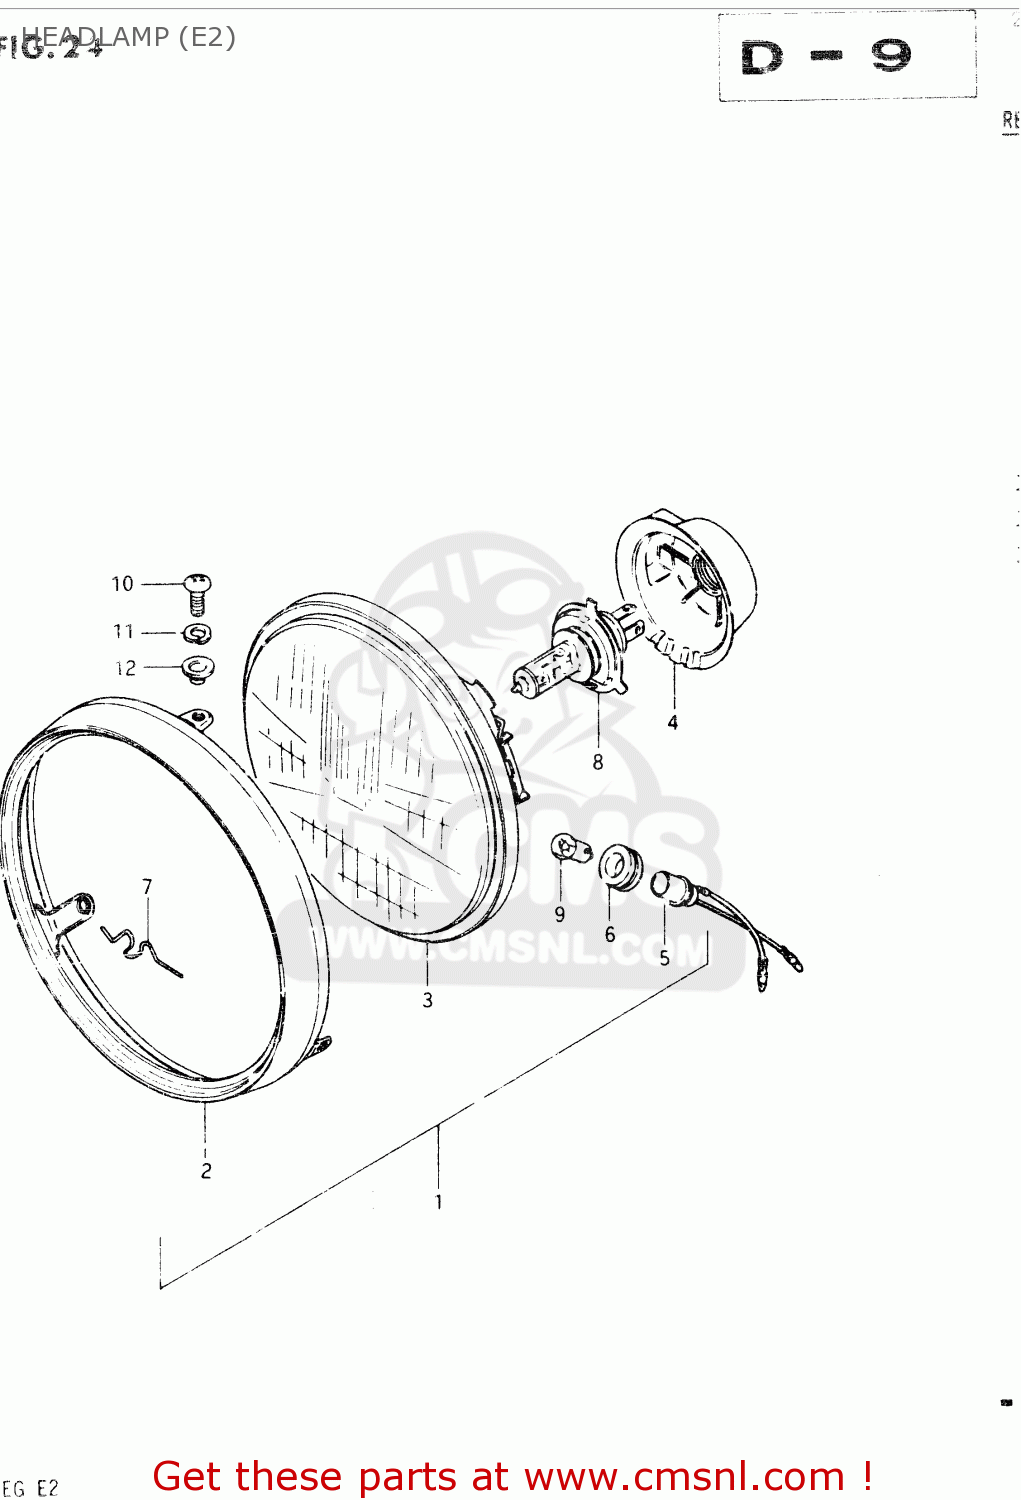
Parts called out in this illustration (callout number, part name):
1	HEADLAMP ASSY
2	RIM
3	LAMP UNIT
4	COVER,SOCKET
5	SOCKET
6	JOINT,RUBBER
7	SPRING
8	BULB(12V60/55W,H4)
9	BULB(12V3.4W,STANLEY,A72A)
10	SCREW
11	WASHER,LOCK
12	WASHER
